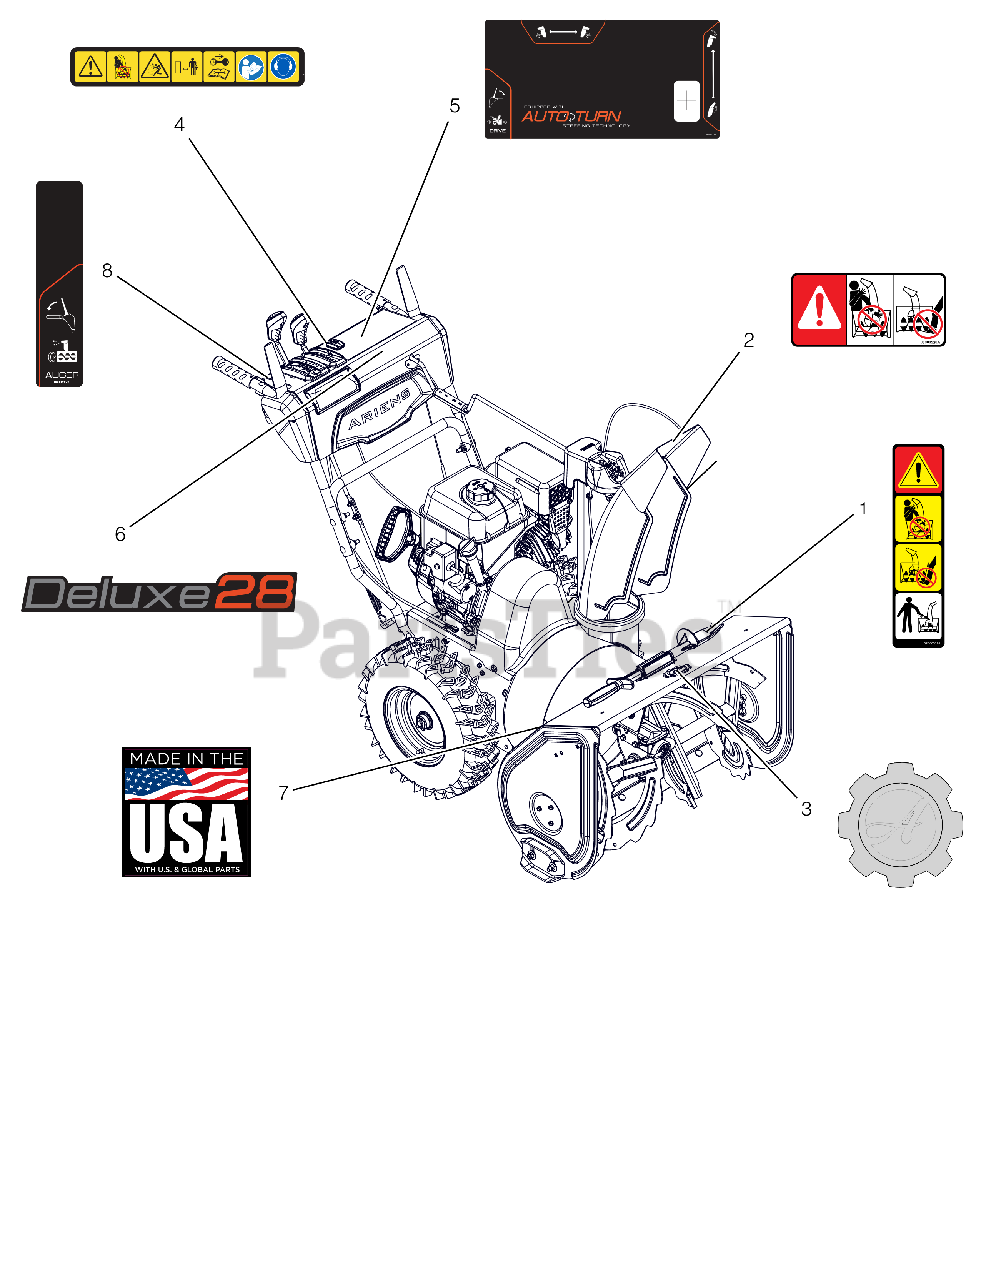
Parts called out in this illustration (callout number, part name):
1	DECAL, DANGER - ROTATING PARTS
2	DECAL, DANGER
3	DECAL, ARIENS-GEAR BADGE -THK
4	DECAL,DASH - SAFETY
5	DECAL,CONTROL-LG ID
6	DECAL, DASH - DELUXE 28
7	DECAL, MADE IN USA
8	DECAL,CONTROL-RH CONTROL
